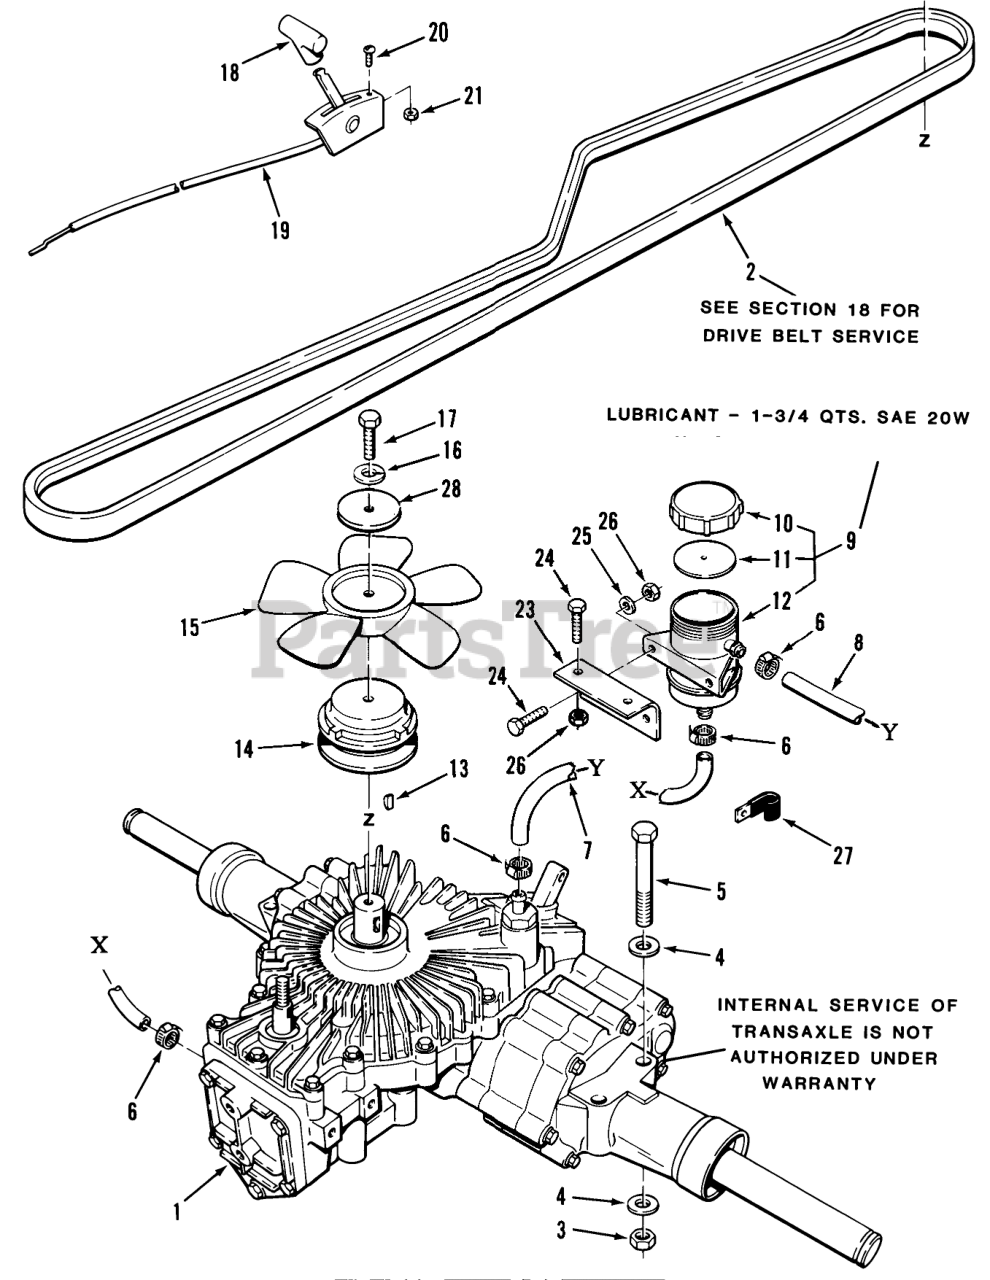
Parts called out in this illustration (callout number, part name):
2	BELT V
4	WASHER 5/16 SAE
11	COVER GASKET
13	HARD HI PRO KEY
15	BLADE-FAN
27	CLIP
28	WASHER
